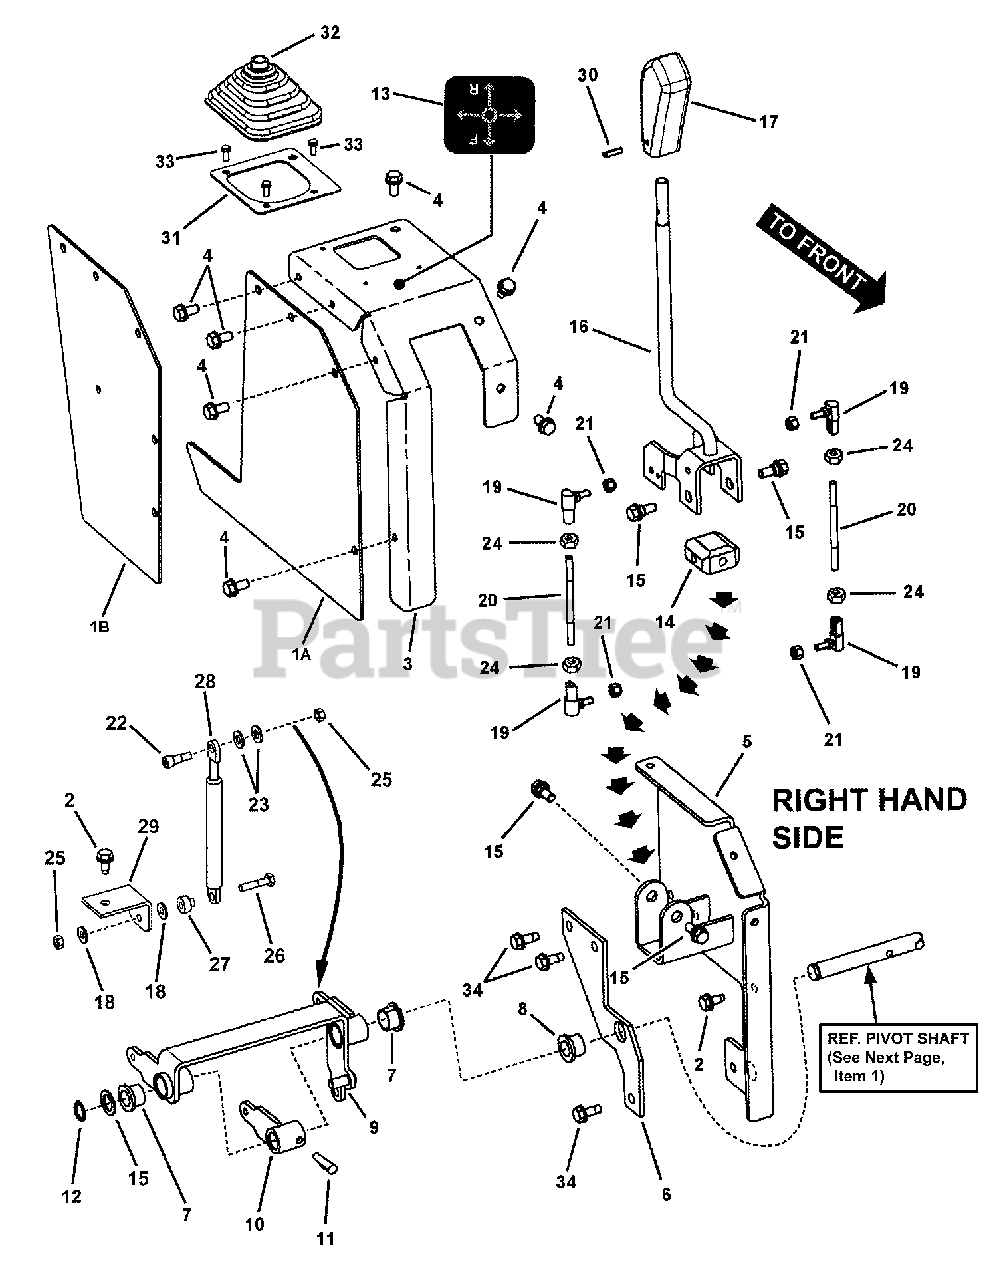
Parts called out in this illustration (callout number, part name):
1A	COVER, Right Hand Outside
1B	COVER, Right Hand Outside
2	SCREW, 5/16-18 x 5/8" Hex Washer Self-Tap
3	LIMITER BRACKET, Right Hand
4	SCREW, 5/16-18 x 5/8" Hex Washer Self-Tap Yellow Zinc
5	WELDMENT, Side Plate Right Hand
6	BRACKET, Shaft Support
7	BUSHING, Teflon Impregnated
8	BUSHING 5/8 x 5/8" Bronze
9	WELDMENT, Joystick Pivot
10	WELDMENT, Bellcrank
11	GROOVE PIN, 1/4 x 1-1/4"
12	RING, 5/8" External Retaining
13	DECAL, Lever Control
14	PIVOT, Joystick Control
15	SHOULDER BOLT, 5/16-18 thread
16	WELDMENT, Joystick Handle
17	LEVER, Shift Handle (Grip)
18	WASHER, .28 x .63 x .06 Flat
19	BALL JOINT, 1/4-28
20	THREADED ROD, 1/4-28 x 3.85 long
21	NUT, 1/4-28 Hex Nyloc
22	SHOULDER BOLT, 1/4-20 thread
23	WASHER, .34 x .69 x .08 Flat
24	HN, 1/4F GR5 YZ
25	NUT, 1/4-20 Hex Center Lock
26	SCREW, 1/4-20 x 1-1/4" Hex Head Cap
27	SPACER, Twin Stick
28	DAMPENER, Hydraulic
29	BRACKET, Dampener
30	ROLL PIN, 3/16 x 3/4"
31	BRACKET, Rubber Boot
32	BOOT, Joystick, Rubber
33	SCREW, #10-24 x 1/2" Hex Washer Self-Tap (Torx)
34	SCREW, 5/16-18 x 3/4" Hex Washer Self-Tap
